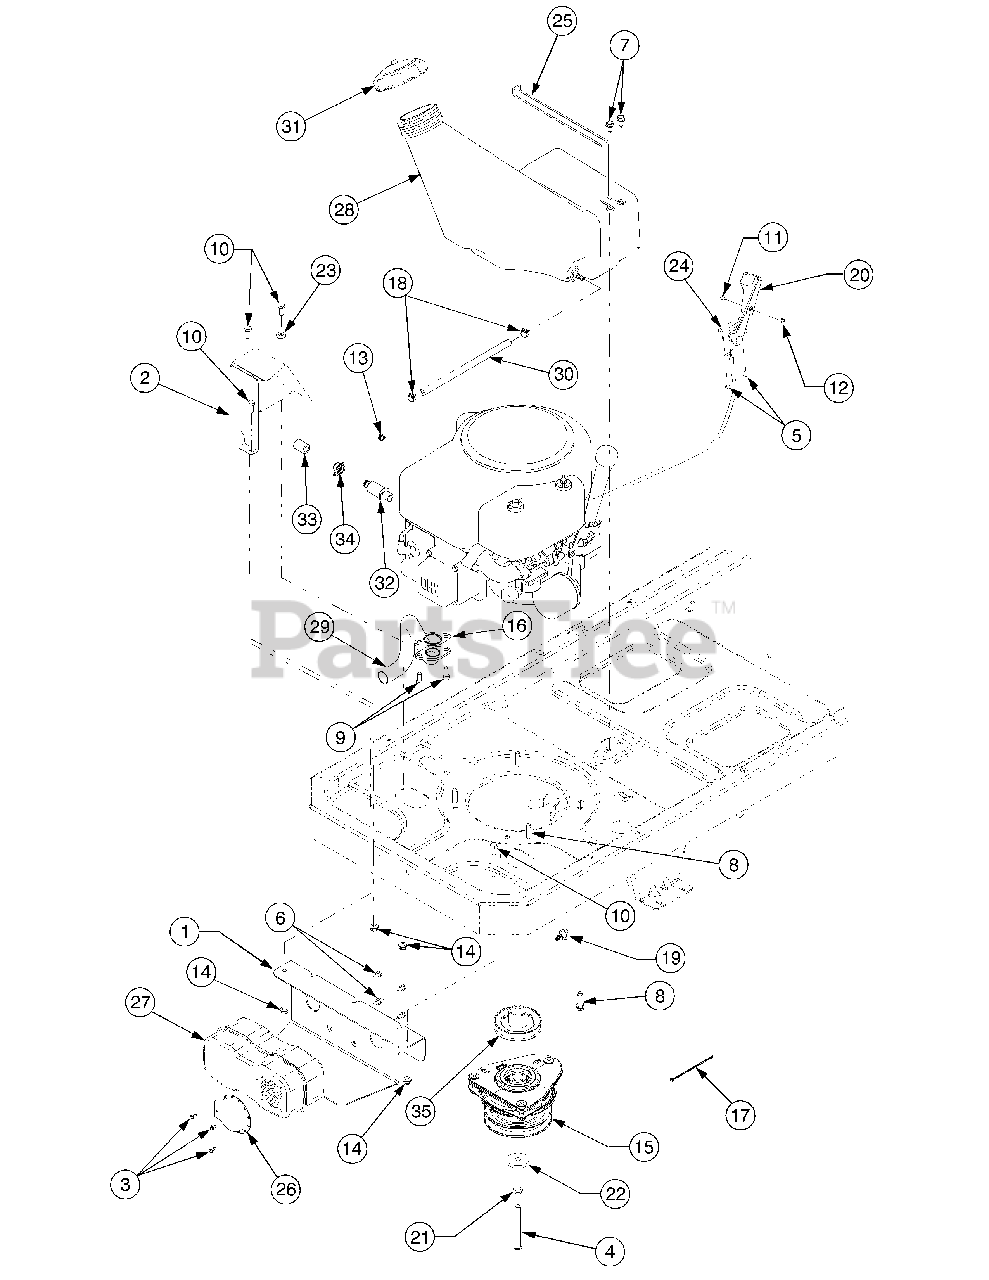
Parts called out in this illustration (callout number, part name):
1	Bracket, Muffler Mounting
2	Shield, Muffler Tube Heat
3	Screw, Hex Wash. Hd. Tapp #8-18 x .5
4	Screw, Hex Cap, 7/16-20 x 4.0 GR5
5	Screw, Hex Wash. Hd. Tapp #12-16 x .5
6	Screw, Hex Wash. Hd. Tapp 1/4-20 x .5
7	Screw, Hex Wash. Hd. Tapp 5/16-12 x .75
8	Screw, Hex Sems Wash. Hd. Tapp ..3/8-16 x 1.25
9	Screw, Socket Hd. 5/16-18 x .75
10	Screw, Hex Cap, 5/16-18 x .75 GR5
11	Screw, Truss Hd. Mach. #8-32 x .375
12	Nut, Hex, #8-32
13	Nut, Sems, 1/4-20
14	Nut, Hx Insert Flange Lck, 5/16-18 GrF
15	Clutch Assembly, Electric PTO
16	Gasket, Exhaust Tec
17	Tie, Cable
18	Clamp, Hose
19	Clip, Cable Retainer
20	Knob, Throttle Control
21	Washer, Lock, 7/16
22	Washer, Flat, .438 x 1.75 x .25
23	Washer, Flat, .344 x .75 x .12
24	Cable, Throttle, 39.0 Lg
25	Wire, Tank Mounting
26	Deflector, Muffler
27	Muffler
28	Tank, Fuel, 3.0 Gal.
29	Pipe, Exhaust
30	Hose, Fuel Line
31	Cap, Fuel
32	Valve, Oil Drain
33	Hose, Oil Drain Extension
34	Cap, Oil Drain Valve
35	Pulley, Drive
